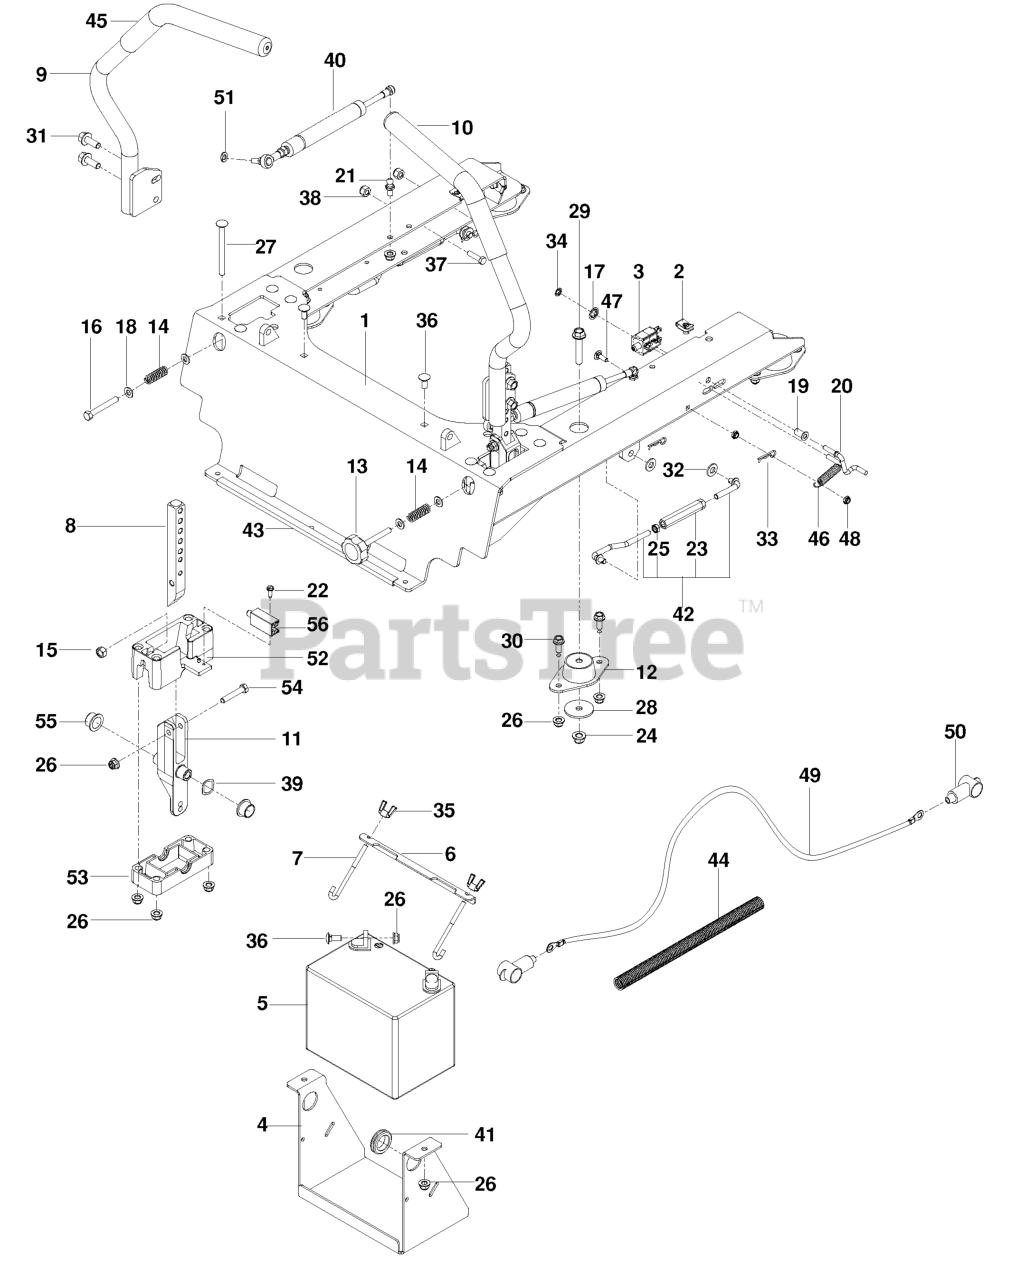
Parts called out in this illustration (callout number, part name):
1	FRAME.SEAT.MOUNT.ORANGE
2	U-CLIP 5/16-18 NUT RETAINER
3	SWITCH, BRAKE 3P
4	BRACKET, BATTERY, BLK
5	BATTERY, 12 V 330 AMP
6	BRACKET, BATTERY MOUNT
7	HOOK, "J"
8	LEVER, MOTION
9	LEVER, W/GRIP, RT
10	LEVER, W/GRIP, LT
11	LEVER, CONTROL
12	MOUNT, ISO
13	KNOB
15	NUT 5/16C HEX
16	HCS 5/16-18 X 2 1/2 TPBLT
17	NUT 3/8 PALNUT RTNG BLK PHOS
18	FLAT WASHER 5/16 SAE
19	BUSHING, 1/4 FLANGE
20	LINK, SWITCH
21	STUD.BALL.10MM
22	SCREW #10 X 1/2 SELF TAPPING
23	TURNBUCKLE, 3/8
24	Nut 3/8-16 Hex Flg Nyloc
25	NUT 3/8-24 JAM
26	5/16-18 NYLOC FLANGE NUT
27	RHSNB 5/16-18 X 3-3/4 GR 5 ZD
28	WASHER, 3/8 SPEC
29	HHFS 3/8-16 X 2.0 GD 5
30	HHFS 5/16-18 X 3/4
31	HHFS 3/8-16 X 1 GRD 5 ZD
32	WASHER 3/8 SAE FLAT
33	HAIRPIN #2
34	NUT PUSH
35	WING NUT 1/4
36	BOLT 5/16C X 3/4" CARRIAGE
37	SCR #10-24 X .75 SKT HD BLK
38	NUT 10-24 NYLOC
39	WASHER, .825 X 1.087, WAVE
40	ASSEMBLY, DAMPENER
41	RUBBER GROMMET
42	ASSEMBLY, SEAT STRUT
43	RP.FLEX TRIM, BLK-LENGTH 1 FT
44	LOOM, SPLIT, CONVOLUTED
45	GRIP - DRIVE LEVER 12"
46	SPRING, EXTENSION
47	RHSNB 1/4C X 3/4
48	JAM NUT 1/4C (2 2 PW01)
49	CABLE, POSITIVE, 55"
51	WASHER.LOCK.HVY.HLCL.SPR.5/16
52	BLOCK, UPPER
53	BLOCK, LOWER
54	HCS 5/16C X 1 3/4
55	BEARING, FLANGE
56	SWITCH, INTERLOCK
